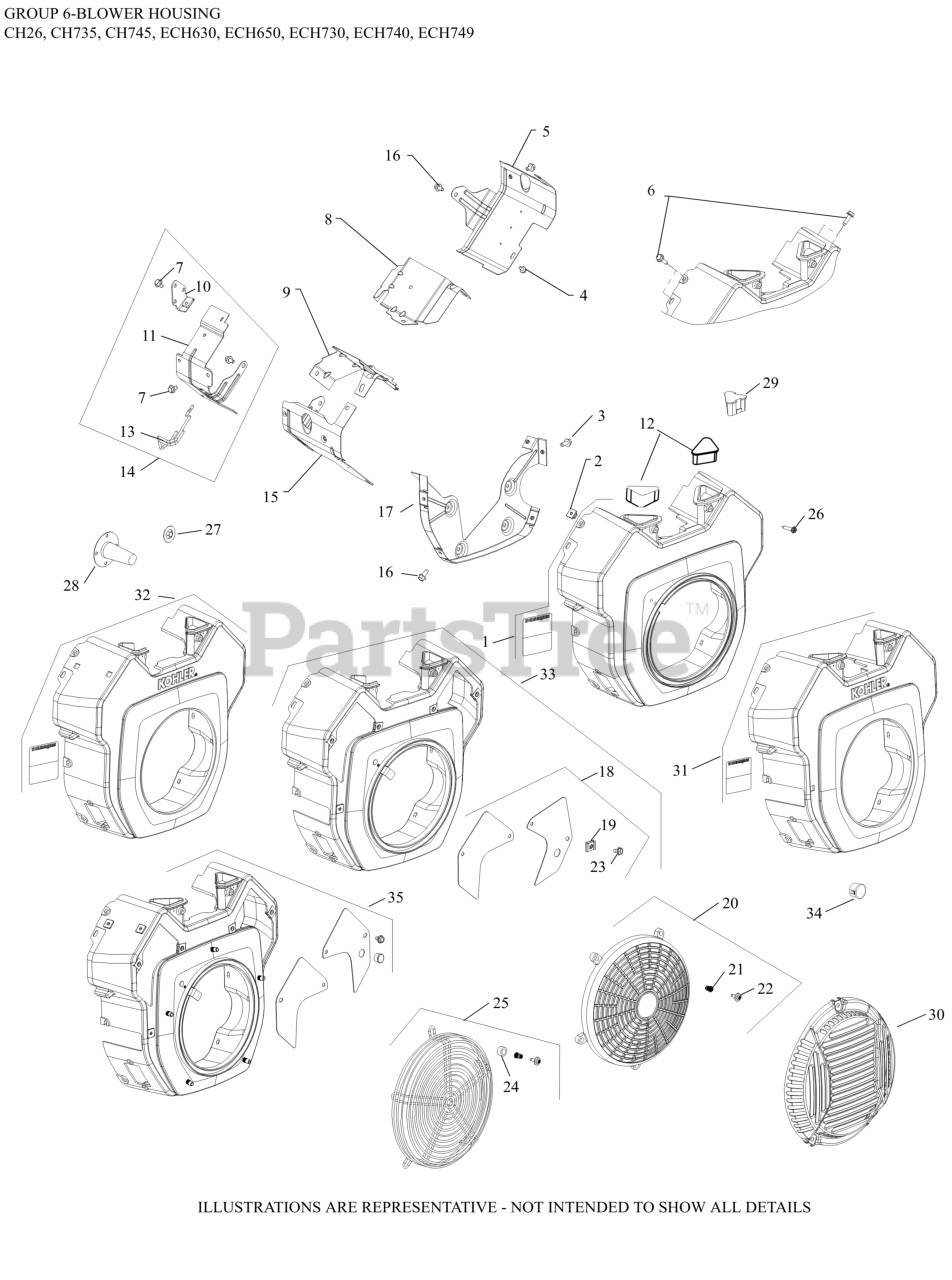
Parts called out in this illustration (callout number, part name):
2	NUT, PLASTIC - BLACK
3	SCREW, THREAD FORMING
4	SCREW, THREAD FORMING
6	SCREW, THREAD FORMING
7	SCREW, FLG M6X1.0X10
8	BAFFLE, VALLEY #1 CYLINDER
9	BAFFLE, VALLEY #2 CYLINDER
16	SCREW, THREAD FORMING
17	KIT, BACKING PLATE
18	KIT, ACCESS PANEL
19	CLIP, BAFFLE MOUNTING
23	SCREW, THREAD FORMING
NI	KIT, CYL BAFFEL #1 SIDE
NI	BAFFLE, LEFT BARREL
NI	KIT, BLOWER HOUSING (SERVICE)-DISC.
